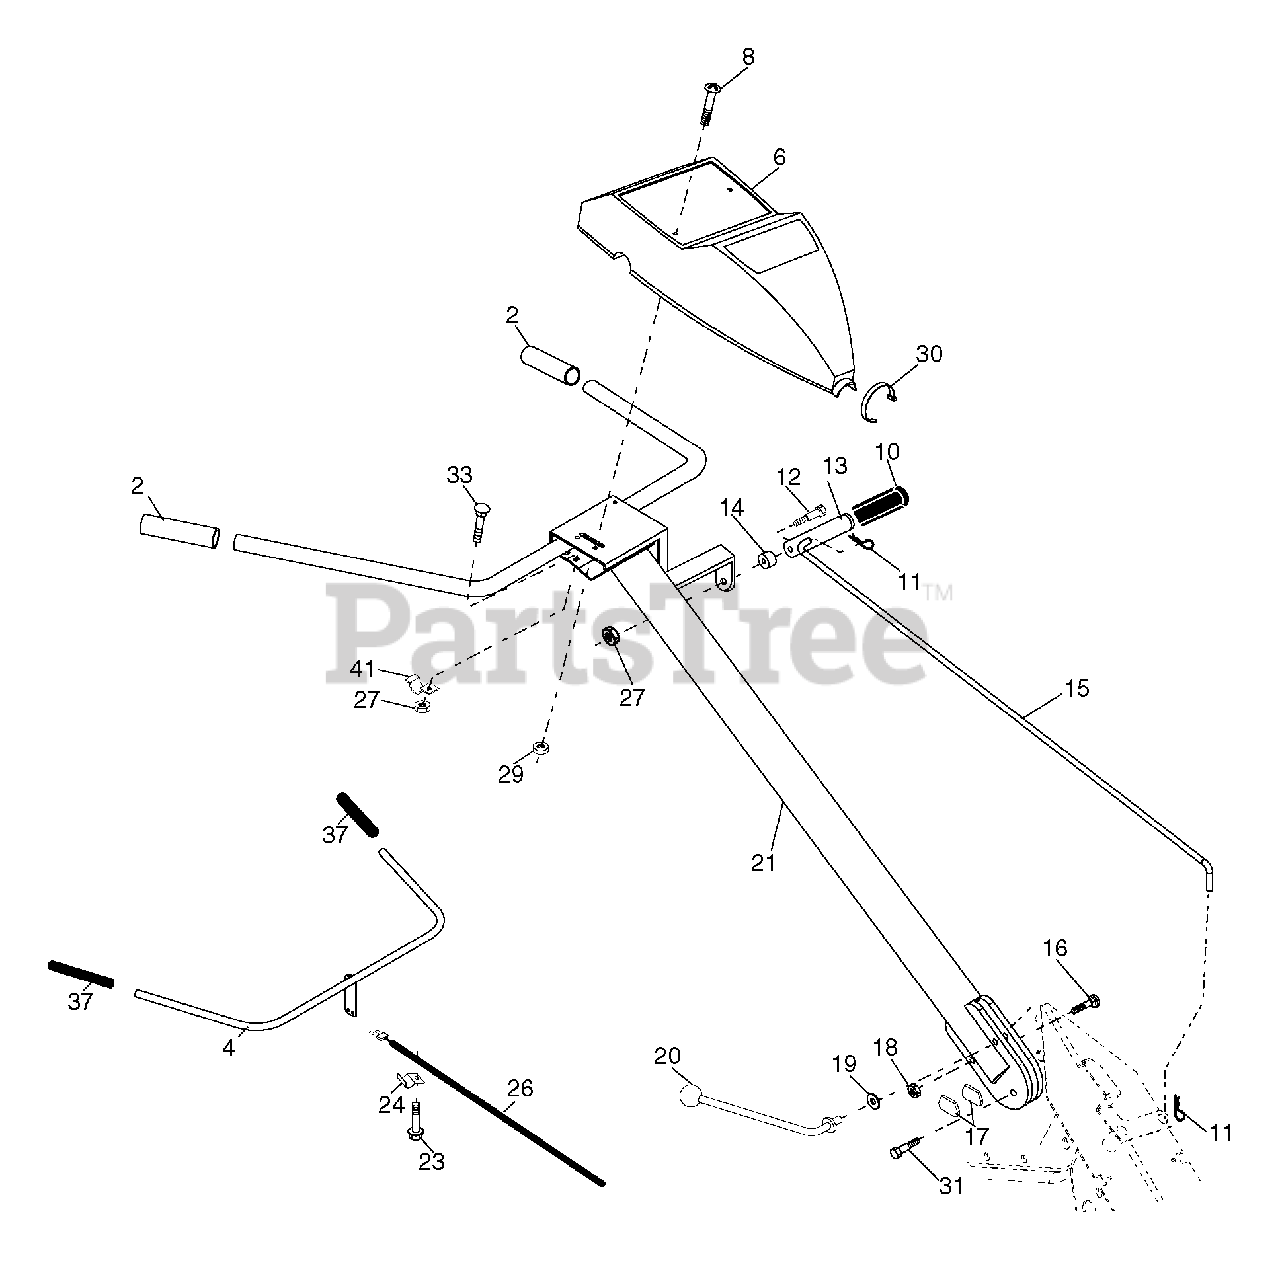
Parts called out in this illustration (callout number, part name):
2	Grip, Handle
4	Bar Assembly, Control
6	Panel, Control
8	Screw, Truss Hd. #10-24 unc x 1/2
10	Grip, Handle
11	Clip, Hairpin
12	Bolt, Shoulder
13	Handle, Shift
14	Grommet, Rubber
15	Rod, Shift
16	Bolt, Carriage 3/8-16 x 1 Gr. 5
17	Lock, Handle
18	Nut, Crownlock 3/8-16 unc
19	Washer 13/32 x 1 x 11 Ga.
20	Lever, Lock, Handle
21	Handle
23	Screw, Hex Washer Hd. Slotted #10-24 x 1/2
26	Cable, Clutch
27	Nut Hex Flange 1/4-20 unc
29	Nut, Keps #10-24 unc
30	Tie, Cable
31	Bolt, Pivot
33	Bolt, Carriage 1/4-20 unc x 1/2
37	Grip, Bar, Control
41	Clamp, Bar, Control
